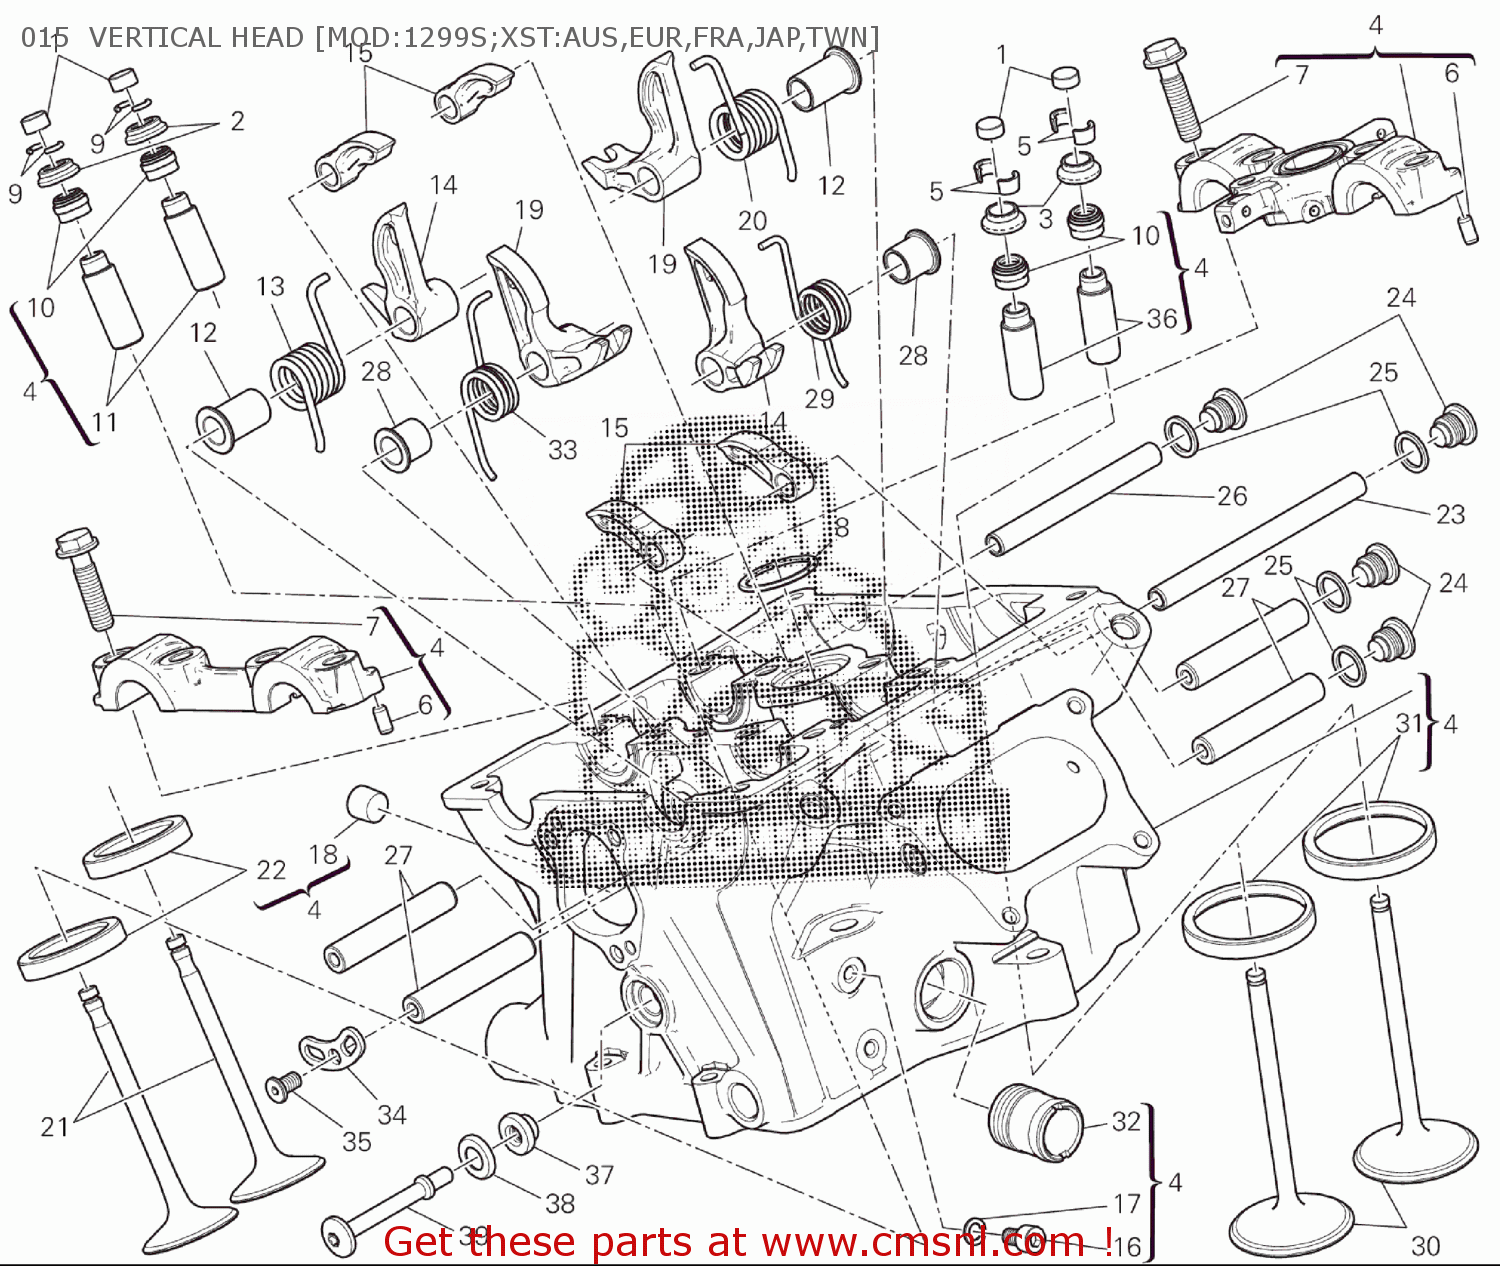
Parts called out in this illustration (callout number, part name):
1	ADJUSTER, OPENING ROCKER ARM 3.9 MM
2	ADJUSTER, CLOSING ROCKER ARM 2.20 MM
3	CLOSE ROCKER ARM ADJUSTMENT 4.55 MM
4	VERTICAL HEAD
5	VALVE COLLET PAIR
6	PIN M5X10
7	SCREW TEF M8X32
8	O-RING 26.64X2.62
9	C RING
10	SEAL VALVE STEM
11	GUIDE, VALVE OVERSIZED 0.03 MM
12	SPACER
13	EXHAUST VALVE RETURN SPRING LH
14	CLOSING ROCKER ARM LEFT
15	OPEN. ROCKER ARM
16	SCREW TCEI M6X10
17	WASHER
18	PLUG
19	CLOSING ROCKER ARM RIGHT
20	EXHAUST VALVE RETURN SPRING RH
21	EXHAUST VALVE
22	SEAT, EXHAUST VALVE
23	OPENING ROCKER SHAFT LONG
24	PLUG
25	GASKET
26	OPENING ROCKER SHAFT SHORT
27	CLOSE ROCKER ARM AXLE
28	SPACER
29	INTAKE VALVE RETURN SPRING LH
30	INTAKE VALVE
31	SEAT, INTAKE VALVE
32	FILLER
33	INTAKE VALVE RETURN SPRING RH
34	PLATE, RETAINER
35	SCREW, SPECIAL
36	GUIDE INTAKE VALVE +0.03 MM
37	VIBRATION DAMPER PAD
38	WASHER
39	SCREW, SPECIAL
